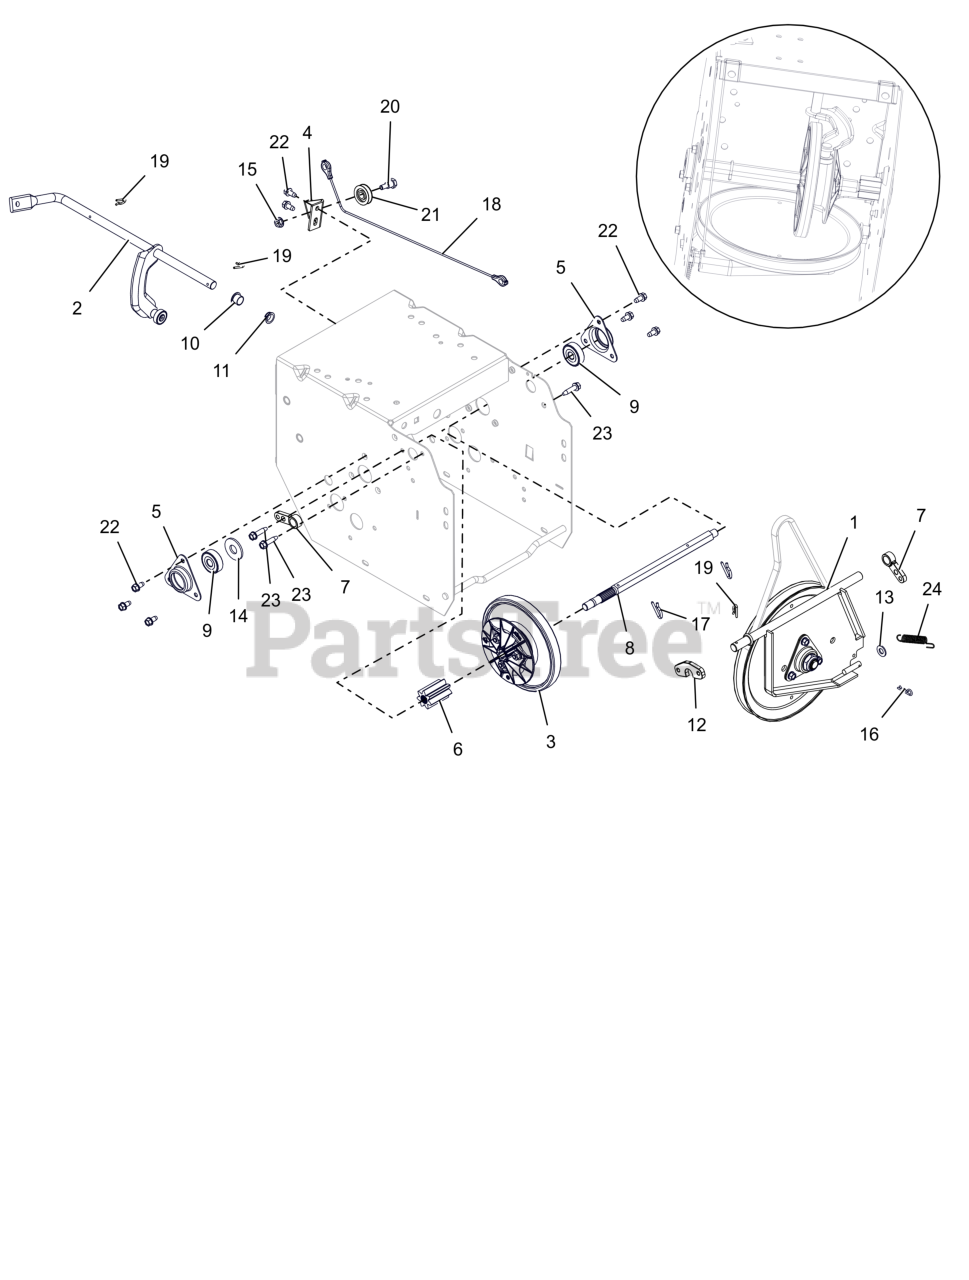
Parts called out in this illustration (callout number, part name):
1	PLATE, SWING - ASSEMBLY
2	ARM, SHIFT-SMALL DASH (ASSY)
3	DISC, FRICTION DRIVE-ASSEMBLY
4	BRACKET, CABLE PULLEY
5	FLANGE, BEARING
6	GEAR, PINION 7 TOOTH W/SPLINE
7	SUPPORT BUSHING, SWING GATE
8	SHAFT, HEX W/SPLINE
9	BRG-BALL .437X1.375X.437
10	BUSHING, POLYLINER-.50 SPLIT
11	BUSHING, POLYLINER-.50 SNAPIN
12	SPACER, SWING GATE
13	WSHR,FLT .344X.688X.065 ZCC
14	WSHR,FLT .563X1.375X.109 ZCC
15	NUT-LK-CTR-FLG .25-20 ZC120
16	PIN, HAIR #213 .08X1.19 ZCC
17	PIN, SPRING CLIP
18	CABLE, LOWER TRACTION (CMPCT)
19	CLIP, SPRING
20	BOLT, SHLDR -.375 X .375 X .25-20
21	PULLEY, CABLE
22	SCR-TAP .25-20X.50 HWH ZCC
23	SCR, TAP .25-20X1.00 TT2000 ZCC
24	SPRING, EXT. .043X.438X1.64
